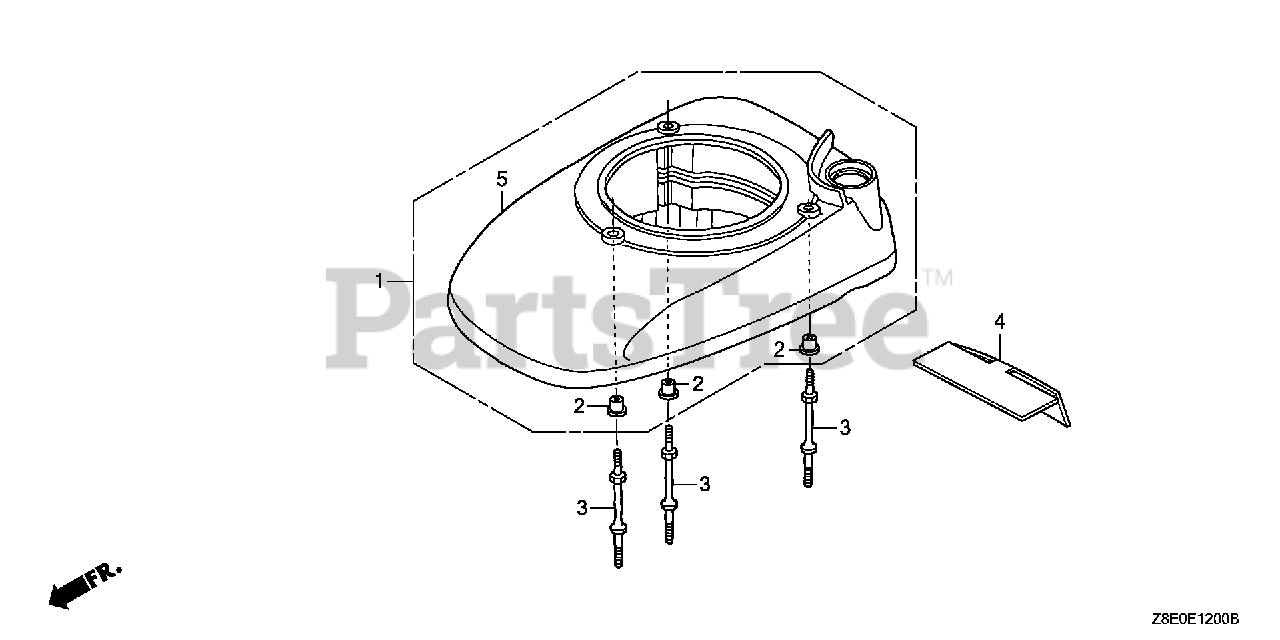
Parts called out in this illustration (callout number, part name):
1	COVER, FAN *R280* (POWER RED)
2	COLLAR, FAN COVER (Honda Code 5580527). (N/A: SEE ASSEMBLY)
3	BOLT, STUD
3	BOLT, STUD (FAN COVER)
4	RUBBER, FAN COVER
5	COVER, FAN *R280* (POWER RED)
